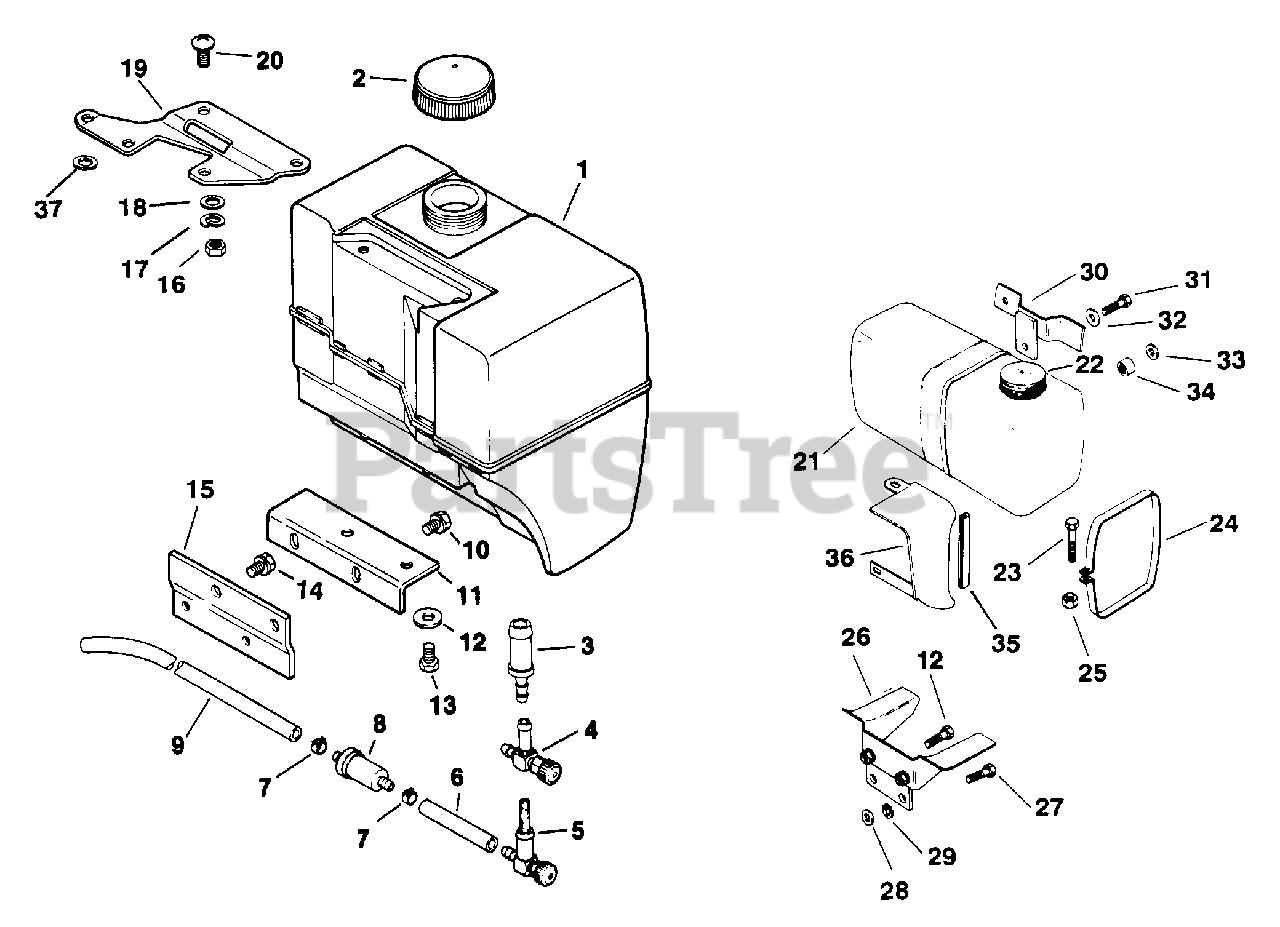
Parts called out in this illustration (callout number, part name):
16	NUT, 1/4-20 GRADE 2 USE 25 100 20-S
17	WASHER, SPRING LOCK 1/4"
20	SCREW, POZ TRS HD 1/4-20X5/8" - DISCONTINUED
